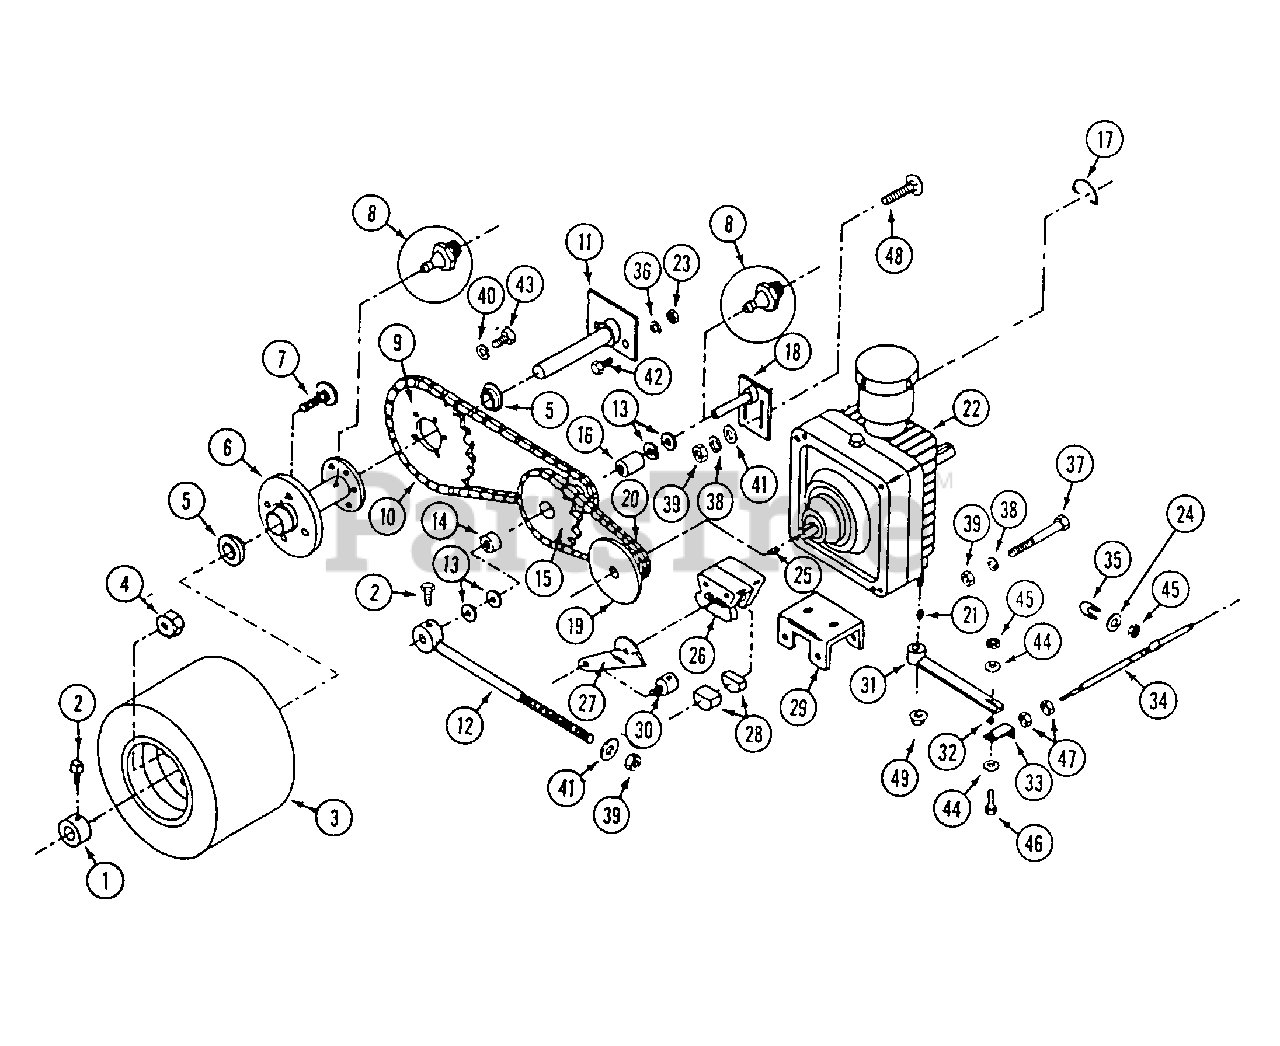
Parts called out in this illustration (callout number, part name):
1	COLLAR - set 1"
2	SCREW - set 5/16" - 18 x 1/2" square head
3	WHEEL ASSEMBLY - drive
4	NUT - lug 1/2" - 20
5	BEARING - wheel
6	HUB - wheel (7" long)
7	BOLT - lug 1/2" - 20 x 1-1/4"
8	FITTING - grease 1/4" - 28 self tapping
9	SPROCKET - final drive
10	CHAIN - final drive (71 pitches)
11	AXLE - drive wheel (8-3/4" shaft)
12	COLLAR - support
13	WASHER - 3/4" 10 ga.
14	BEARING - idler sprocket 1/2"
15	SPROCKET - idler
16	BEARING - idler sprocket 3/4"
17	CLIP - transmission dump valve
18	SHAFT - idler sprocket
19	SPROCKET - transmission
20	CHAIN - primary drive
21	KEY - 1/8" x 3/8" Woodruff
22	TRANSMISSION - L.H. (CW)
23	NUT - 1/2" - 13
24	WASHER - 1/4"
25	KEY - woodruff 1/8" x 1/2"
26	CALIPER - brake
27	LEVER - caliper L.H.
27	LEVER - caliper R.H.
28	PAD - brake (set)
29	BRACKET - caliper
30	COLLAR - caliper rod
31	ARM - transmission L.H.
31	ARM - transmission R.H.
32	BUSHING - cable end
33	END - steering cable
34	CABLE - steering
35	CLAMP - steering cable
36	LOCKWASHER - 1/2"
37	BOLT - 3/8" - 16 x 3"
38	LOCKWASHER - 3/8"
39	NUT - 3/8" - 16
40	LOCKWASHER - 5/16"
41	WASHER - 3/8"
42	BOLT - 1/2" - 13 x 1-1/2"
43	BOLT - 5/16" 18 x 1"
44	WASHER - 1/4"
45	NUT - 1/4" - 20 lock
46	BOLT - 1/4" - 20 x 1"
47	NUT - #10 - 32 lock
48	BOLT - carriage 3/8" - 16 x 1-1/4"
49	NUT - 3/8" - 16 flange lock
